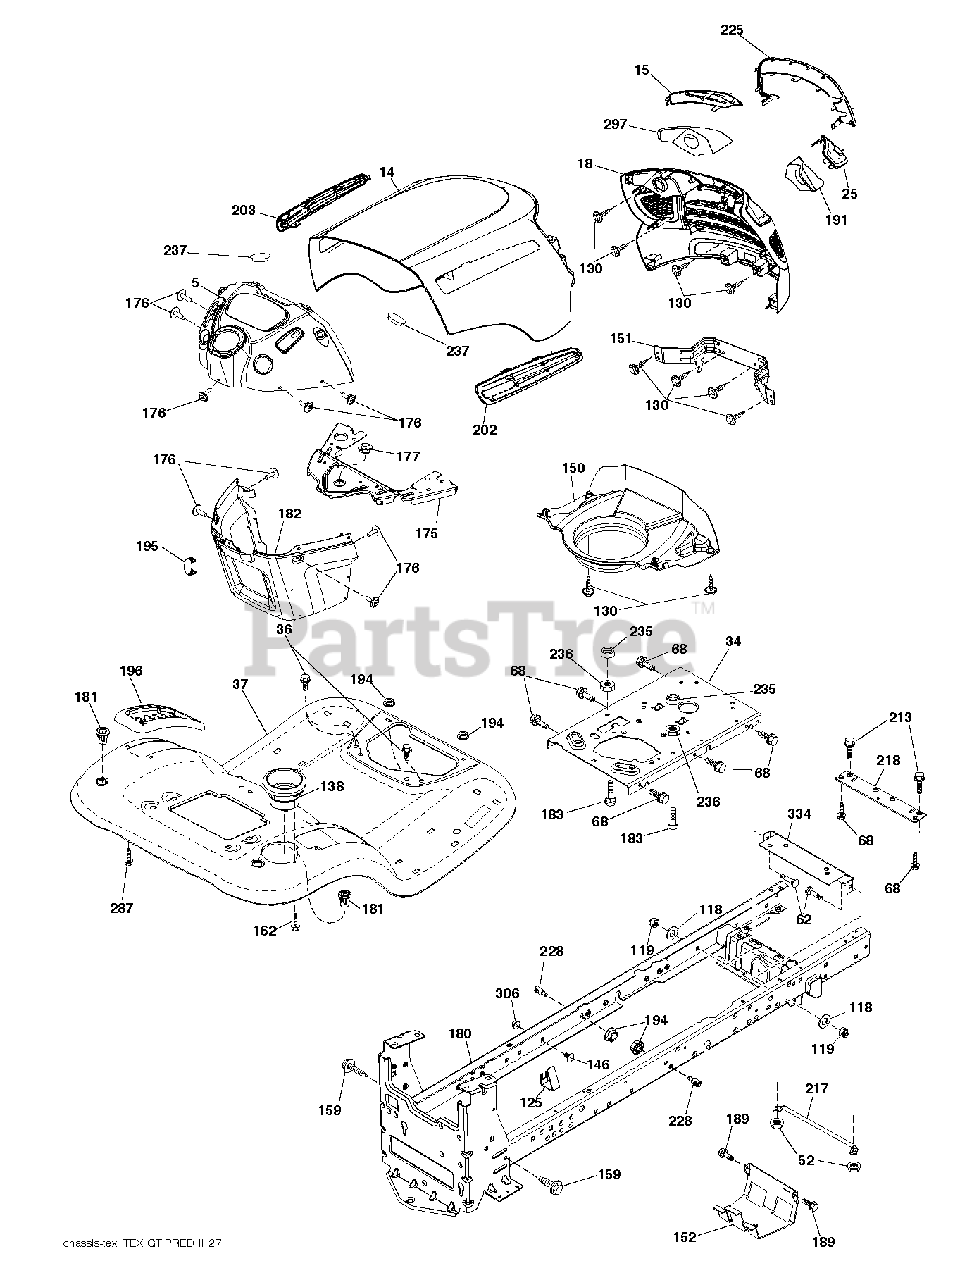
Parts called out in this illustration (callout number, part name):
5	DASH.UPPER.PREDATOR.YT/GT
14	HOOD.PNT.PREDATOR.YT/GT.BLACK
15	LENS.MCCULLOCH.GT.LH
18	GRILLE.PREDGT2.GEN
25	Lens, RH Mcculloch GT
34	PLATE.ENGINE.WELDED.CHASSIS
36	SCREW 5/16"
37	FENDER.TLT.W/CPH.428
52	LOCKNUT
68	SCREW LT
119	LOCKNUT
125	CLIP.FUEL.LINE
130	SCREW.#10 X 0.750.BOS (2 2)
138	CUPHOLDER.TL.TEX.BLACK
146	BOLT.RDHD.SHT.SQNK.3/8-16X5/8
150	PREDATOR.YT.GT.HOOD.AIR DUCT
151	BRACKET.PIVOT.PREDATOR
152	SHIELD.BROWNING.W/TEX
159	SCREW, 3/8-16X3/4
162	SCREW.HI-LO.CONSOLE
175	PLATE.CROSSMEMBER.HUSQ
176	SCREW.#10-24X5/8.RN.QU
177	BUSHING STEERING
180	CHASSIS
181	FEND/FTRST.PCH.CPH.NFW
182	DASH LOWER.HUSQ.PRED NO CRUISE
183	BOLT.5/16-18X1-1/4 FULL THD
189	SCREW
191	REFLECTOR.MCCULLOCH.GT.RH
194	NUT LOCK HEX FLANGE 5/16-18
195	PLUG.HOLE.DASH.
202	VENT.SIDE.HOOD.RH.PREDATOR.BLK
203	VENT.SIDE.HOOD.LH.PREDATOR.BLK
213	BOLT
217	ROD.PIVOT.HOOD
218	X-PIECE.HOOD.STOP.NON/
228	STUD.FASTNER.W/ANTI-ROTATE
235	SPACER FENDER
236	NUT.CENTERLOCK.5/16-
237	PLUG.MOUNT.CARGO.BLK
287	SCREW 1/4X20
297	REFLECTOR.MCCULLOCH.GT.LH
306	NUT LOCK FLG 3/8-16 UNC
334	BRACKET.ENGINE
